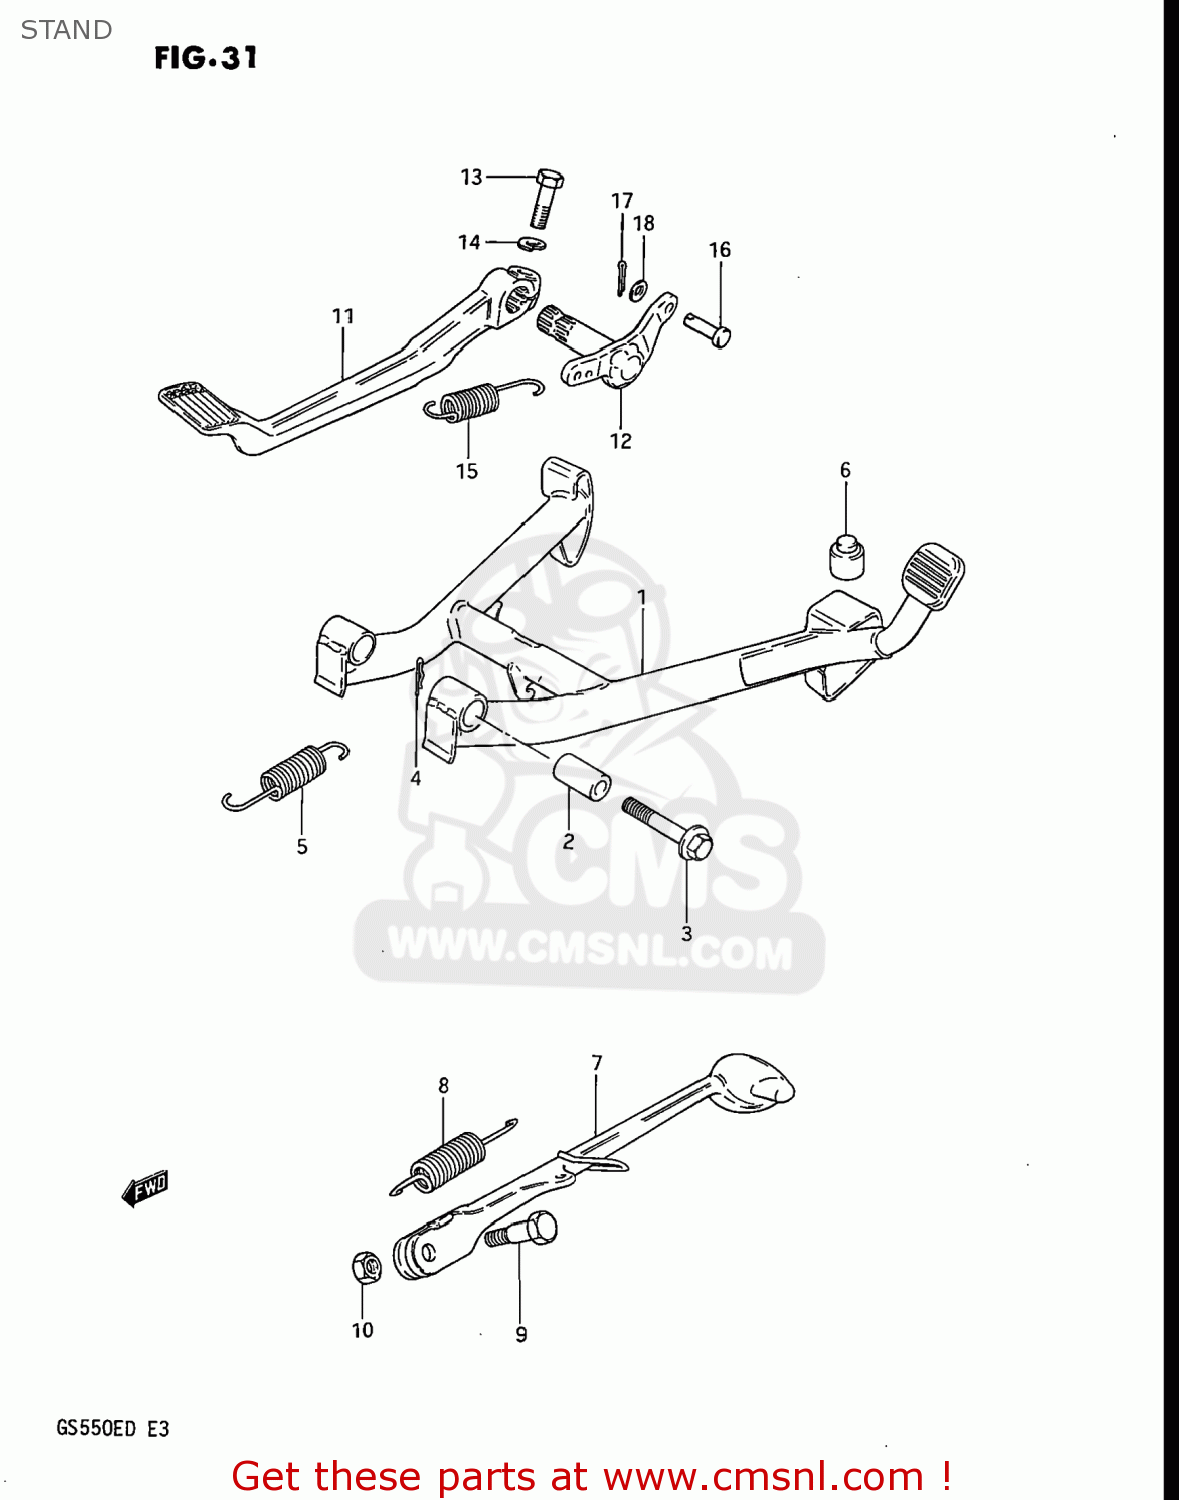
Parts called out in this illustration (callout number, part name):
1	STAND,CENTER
2	SPACER (10.5X16X31.8)
3	BOLT 10X50
4	CLIP
5	SPRING
6	CUSHION
7	STAND,SIDE
8	SPRING
9	BOLT L:30
10	NUT
11	PEDAL,BRAKE
12	ARM,BRAKE PEDAL ROD
13	BOLT
14	LOCK WASHER
15	SPRING
16	PIN
17	PIN
18	WASHER
